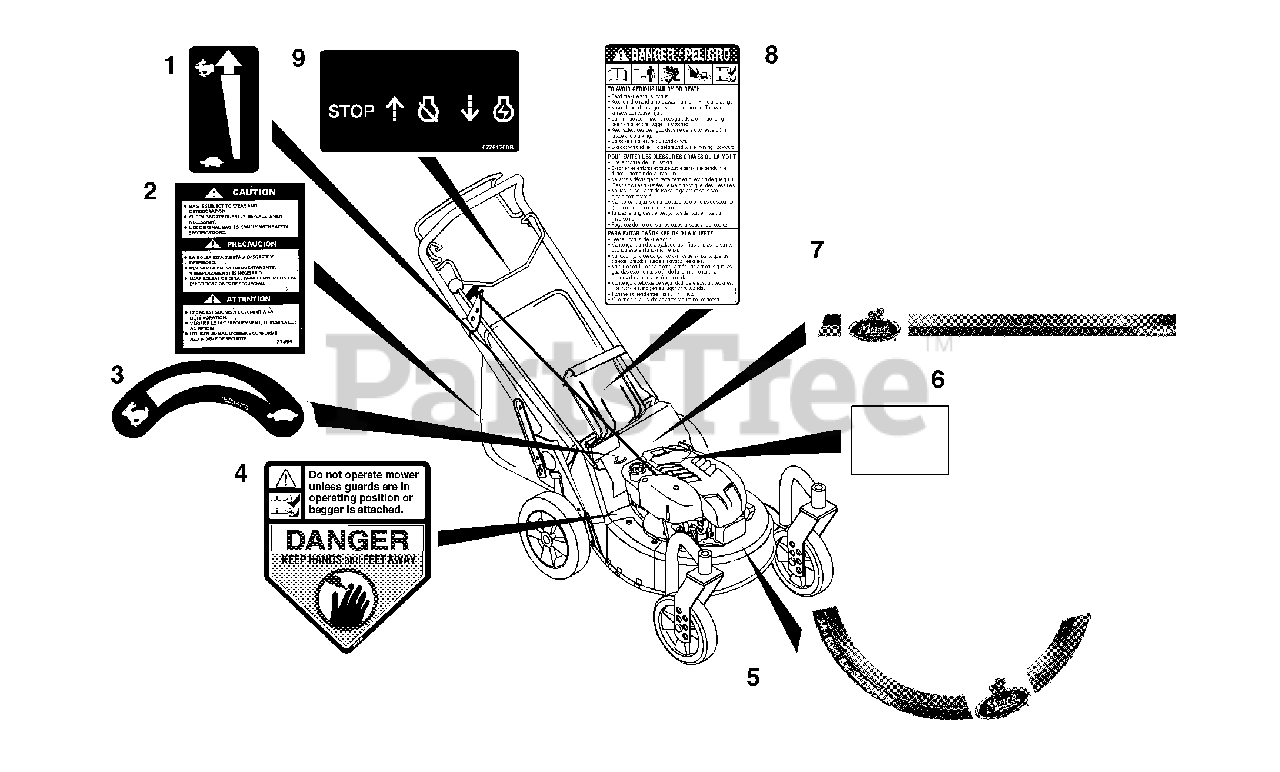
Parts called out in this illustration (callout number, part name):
1	DECAL-SPEED CONTROL
2	LABEL - BAGGER 21"
3	DECAL, TURTLE & RABBIT
4	DECAL, CPSC DANGER
5	DECAL, DECK MACK
6	DECAL, BRIGGS 6.5HP
7	DECAL, MACK DRIVE COVER
8	DECAL, BILINGUAL DANGER
9	DECAL - ENGINE CONTROL
